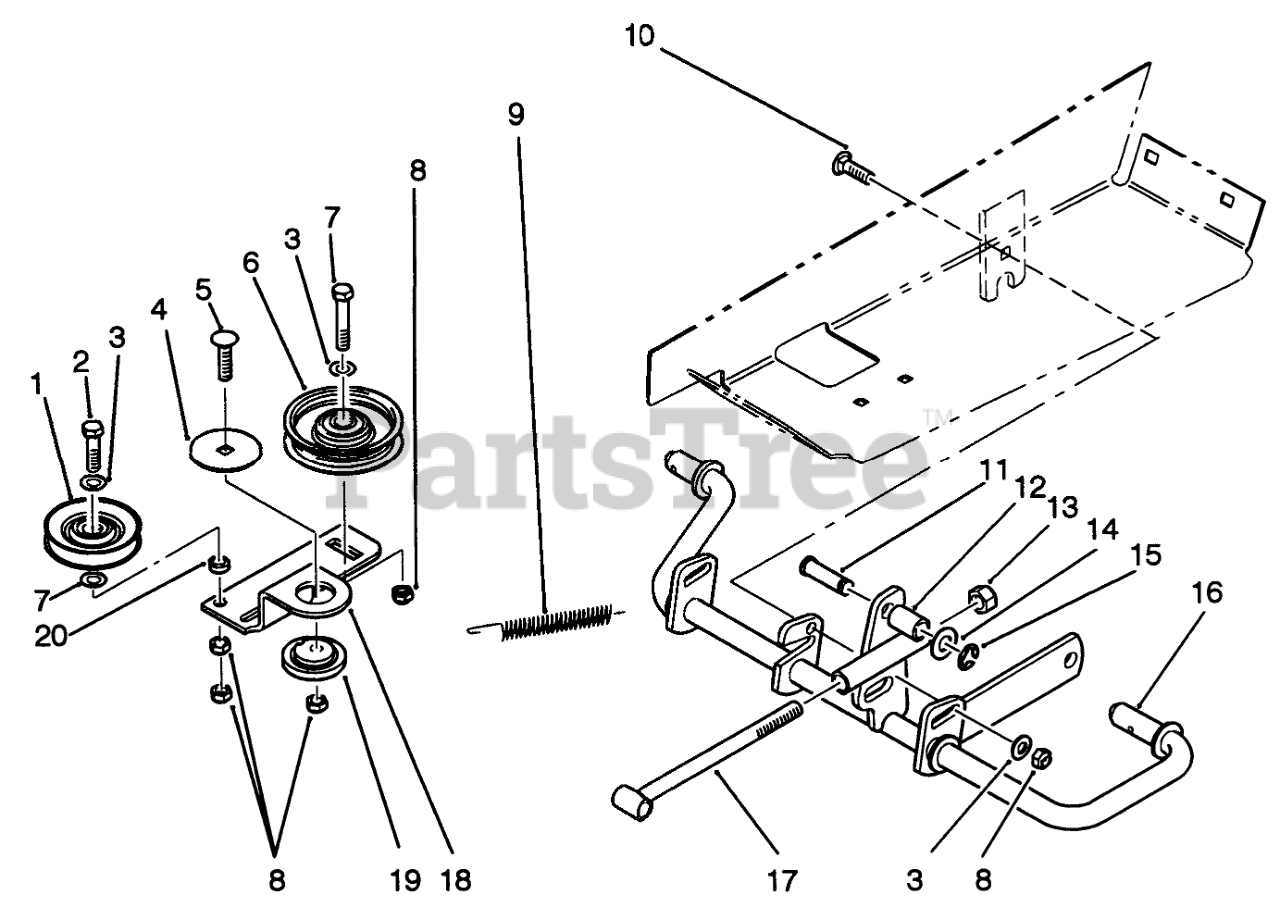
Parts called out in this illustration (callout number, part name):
1	Pulley
2	BOLT
3	WASHER-FLAT
4	WASHER-BEARING
5	Bolt
6	Idler Pulley
7	SCREW-HH
8	NUT-LOCK, NI
9	SPRING - CLUTCH
10	SCREW-CARR
13	NUT-LOCK, NI
14	NUT-LOCK, NI
15	RING-RETAINING, EXTERNAL
16	Shaft
18	ARM-IDLER
19	BUSHING
20	SPACER
